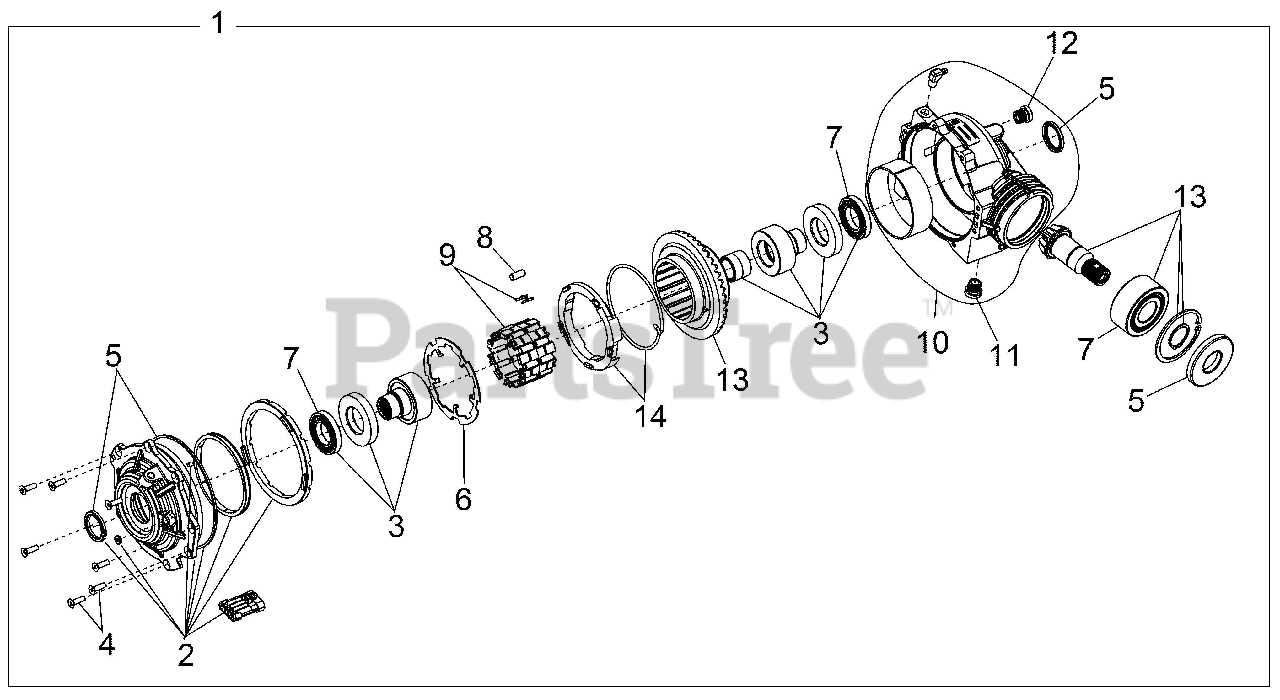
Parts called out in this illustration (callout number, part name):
1	ASM-GEARCASE,FRONT
2	ASM-COVER,OUTPUT
3	KIT-HUB,ASM
4	KIT-FASTENER
5	KIT-SEAL REPAIR
6	PLATE-4WD ARMATURE
7	BEARING-PINION,5306
8	K-CLUTCH ROLLS
9	ASSY, ROLL CAGE ZN
10	KIT-GEARCASE ASM
11	DRAIN PLUG(6203-95-010)
12	FILL PLUG(1300-04-001-T)
13	K-GEAR CLTCH HOUSING & PINION
14	K-TORSION SPRING & RETAINER
